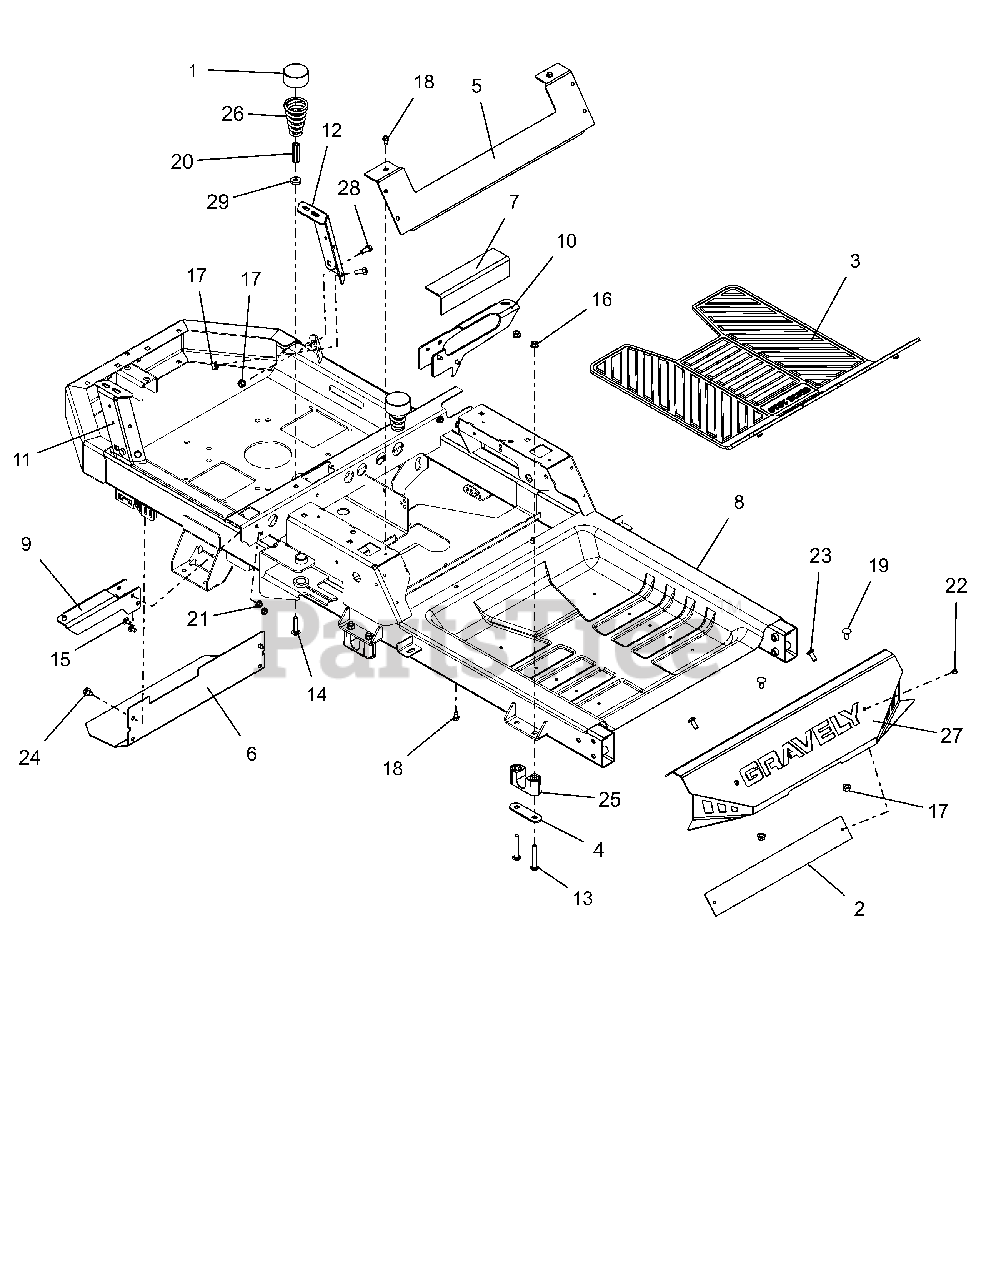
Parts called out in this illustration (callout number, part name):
2	PLATE, BACK FOOT-REST XL
3	FLOOR MAT, RUBBER - GRAVELY
4	PLATE, BEARING SUPPORT
5	PLATE, SEAT KICK
6	HEAT, SHIELD
7	PAD, RUBBER-TANK
8	KIT, ZT-X/XL FRAME SERVICE
9	BRKT,CROSS EXTENSION - LH
10	BRKT,CROSS EXTENSTION - RH
11	MOUNT,FENDER-RH EXTENSION
12	MOUNT,FENDER-LH EXTENSION
13	BLT-RDHDSQSHNK .31-18X2.25 YWZ
14	BLT,RHSN .31-18X1.50 G5 ZCC
15	BLT, RHSSN.25-20X.500 G5 ZCC
16	NUT,LK-CTR-FLG .31-18 GF ZCC
17	NUT-LK-TOP-FLG .312-18 GF ZCC
18	SCR-TAP .25-20X.50 HWH ZCC
19	BLT,RHSN .31-18X.75 G5 ZCC
20	NUT, COUPLING 5/16-18 X 1 3/4
21	NUT-LK-CTR-FLG .25-20 ZC120
22	RIVET, .1875 AL/AL .126-.250
23	SCR-RDHDSKTAP .31-18 X .75
24	SCR,TAP .312-18X.50 HWH TR ZCC
25	BSHG, DECK LIFT PIVOT
26	SPRING, SEAT
27	KIT,FOOTPLATE W/DECAL G- XL
28	BLT,HEX .31-18X.75 G5 ZCC
29	WSHR, FLT .328X.870X.179 ZCC
